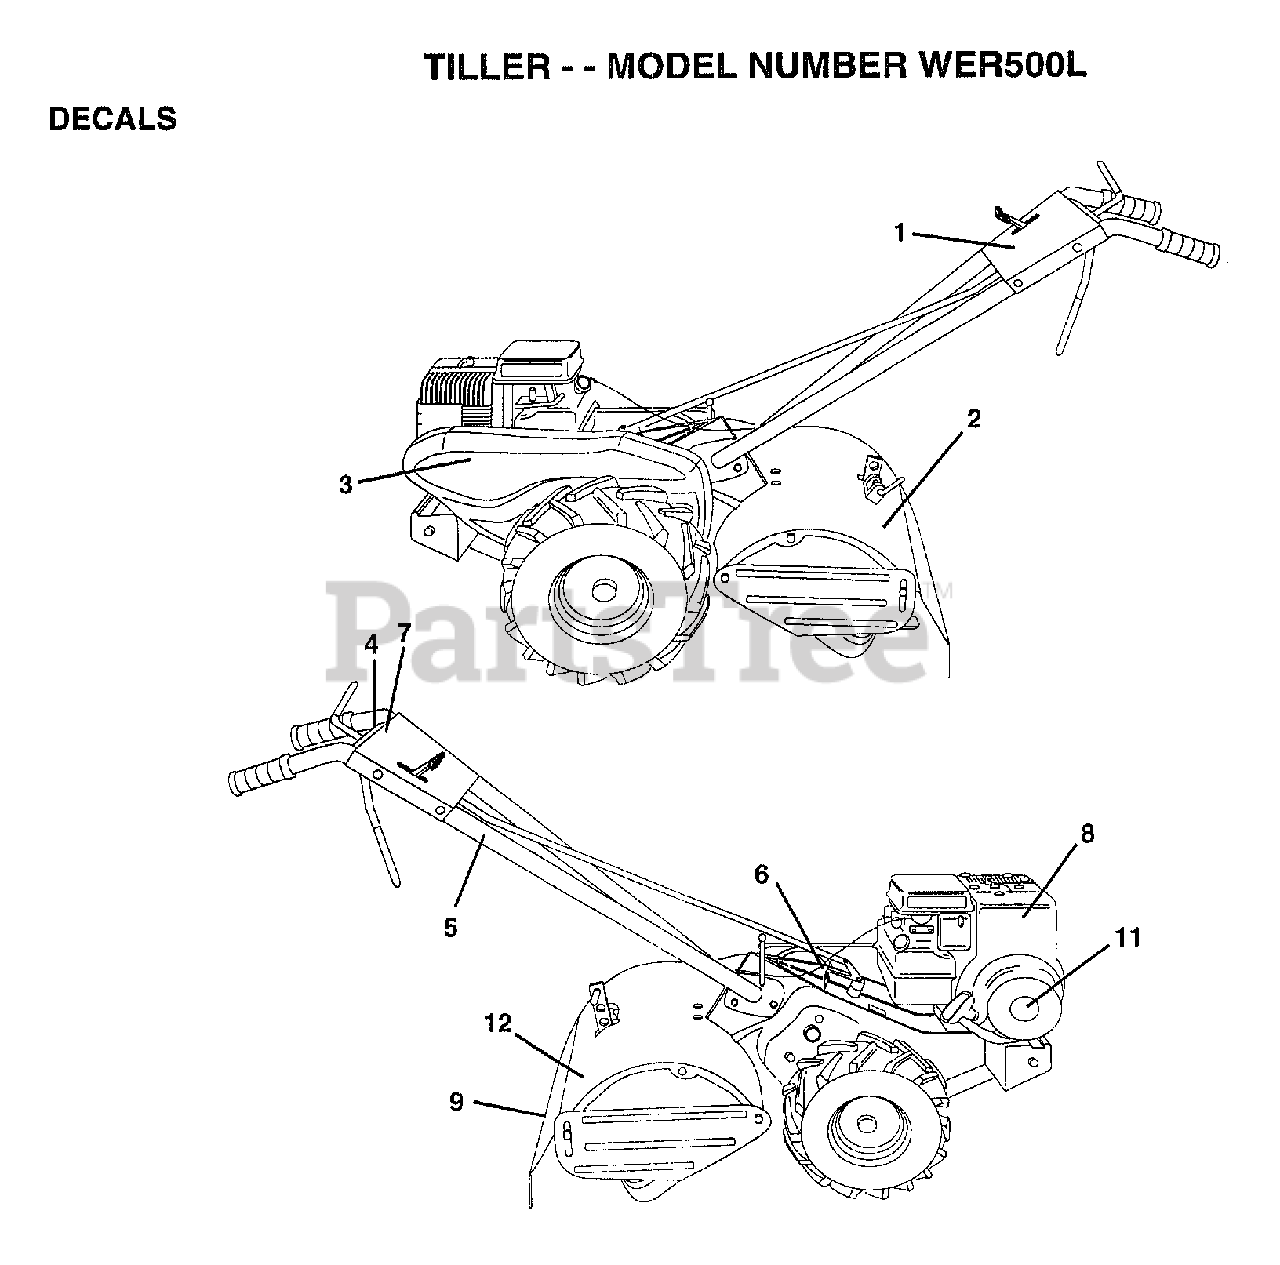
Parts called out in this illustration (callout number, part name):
2	DECAL.DESCRIPTION
3	"DECAL,LOGO"
5	DECAL TI
6	DECAL CRT
7	DECAL REVERSE
12	DECAL.CAUTION
